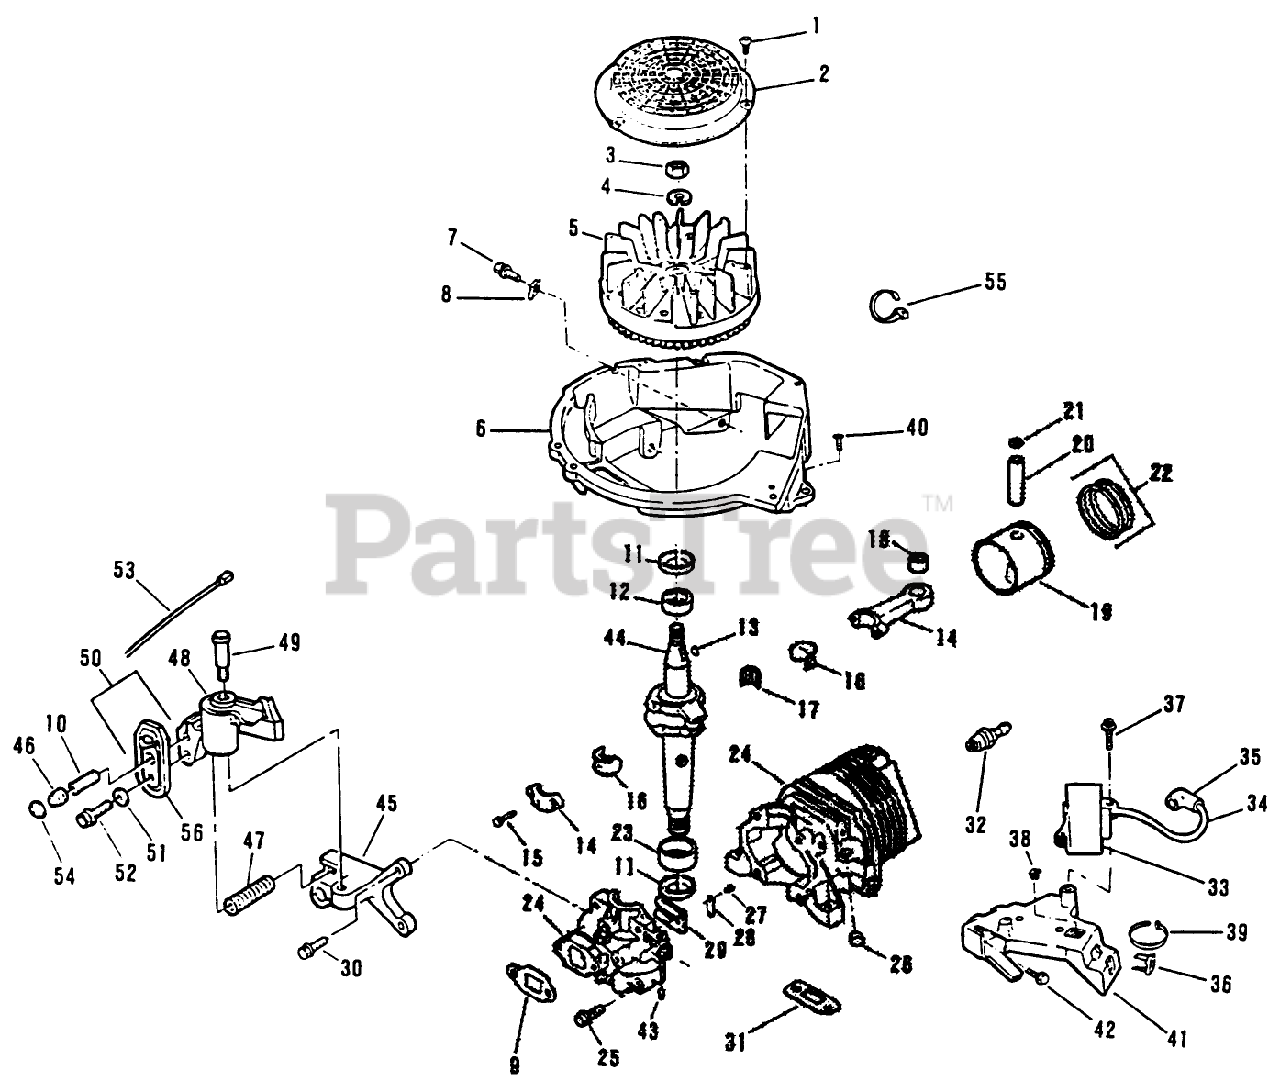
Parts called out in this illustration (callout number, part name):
1	SCREW F
3	NUT
5	FLYWHEEL ASSY F
7	SCREW-SEMS
9	GASKET CARB S
10	SPRING
11	SEAL-OIL
12	BEARING V
13	KEY
15	SCREW-HSH
16	LINER ASM
17	BEARING-NEEDLE
18	BEARING AY F
21	RING-RETAINING
23	BEARING V
25	SCREW-H.W.HD. F
26	PLUG-CORE VF
27	SCREW-HH
28	PLATE-BACKUP, REED
30	SCREW
31	GASKET-EXHAUST F
34	HT LEAD&COVER XEV
36	NUT-CLIP
38	NUT-CLIP
40	SCREW F
41	C.D. BRKT F
45	BRACKET-BRAKE F
46	ACTUATOR-LEVER, BRAKE
47	SPRING-BRAKE
49	SCREW-SHOULDER
51	WASHER
53	WIRE LEAD AY F
54	RETAINER S
